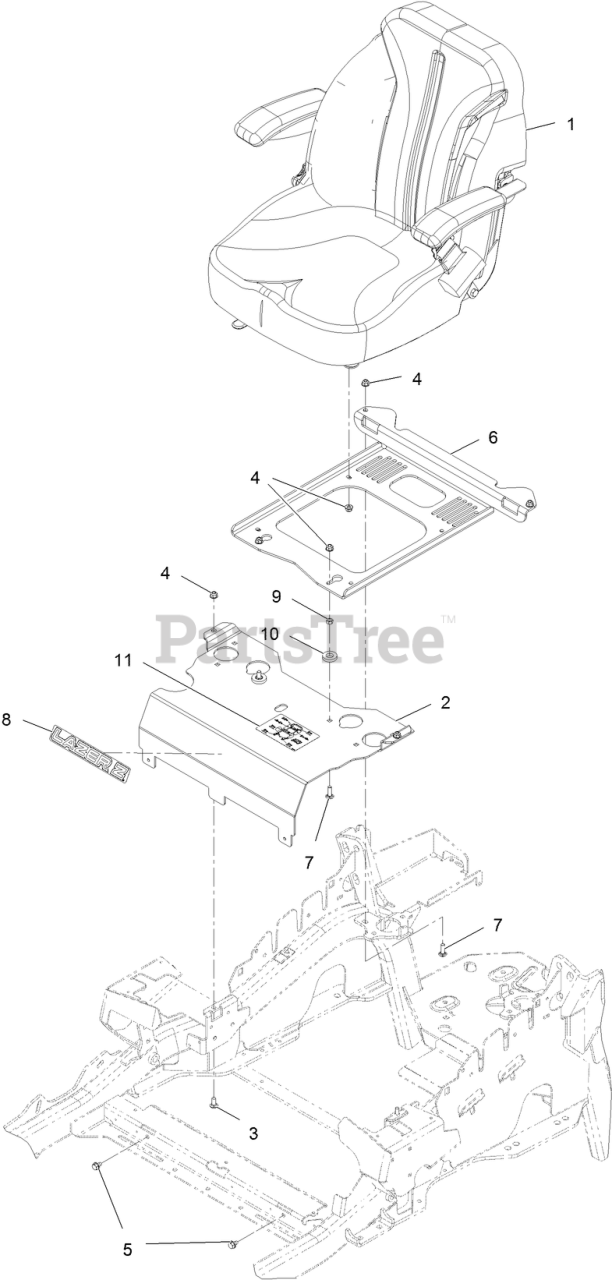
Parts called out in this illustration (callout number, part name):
1	ASM-SEAT LZE
2	Panel-Front, Seat Mount
3	SCREW-CARR
4	NUT-HF, NI
6	PLATE-SUPPORT, SEAT
7	SCREW-CARR
8	DECAL, LAZER MODEL
9	NUT-HEX
11	DECAL-SERVICE AID
